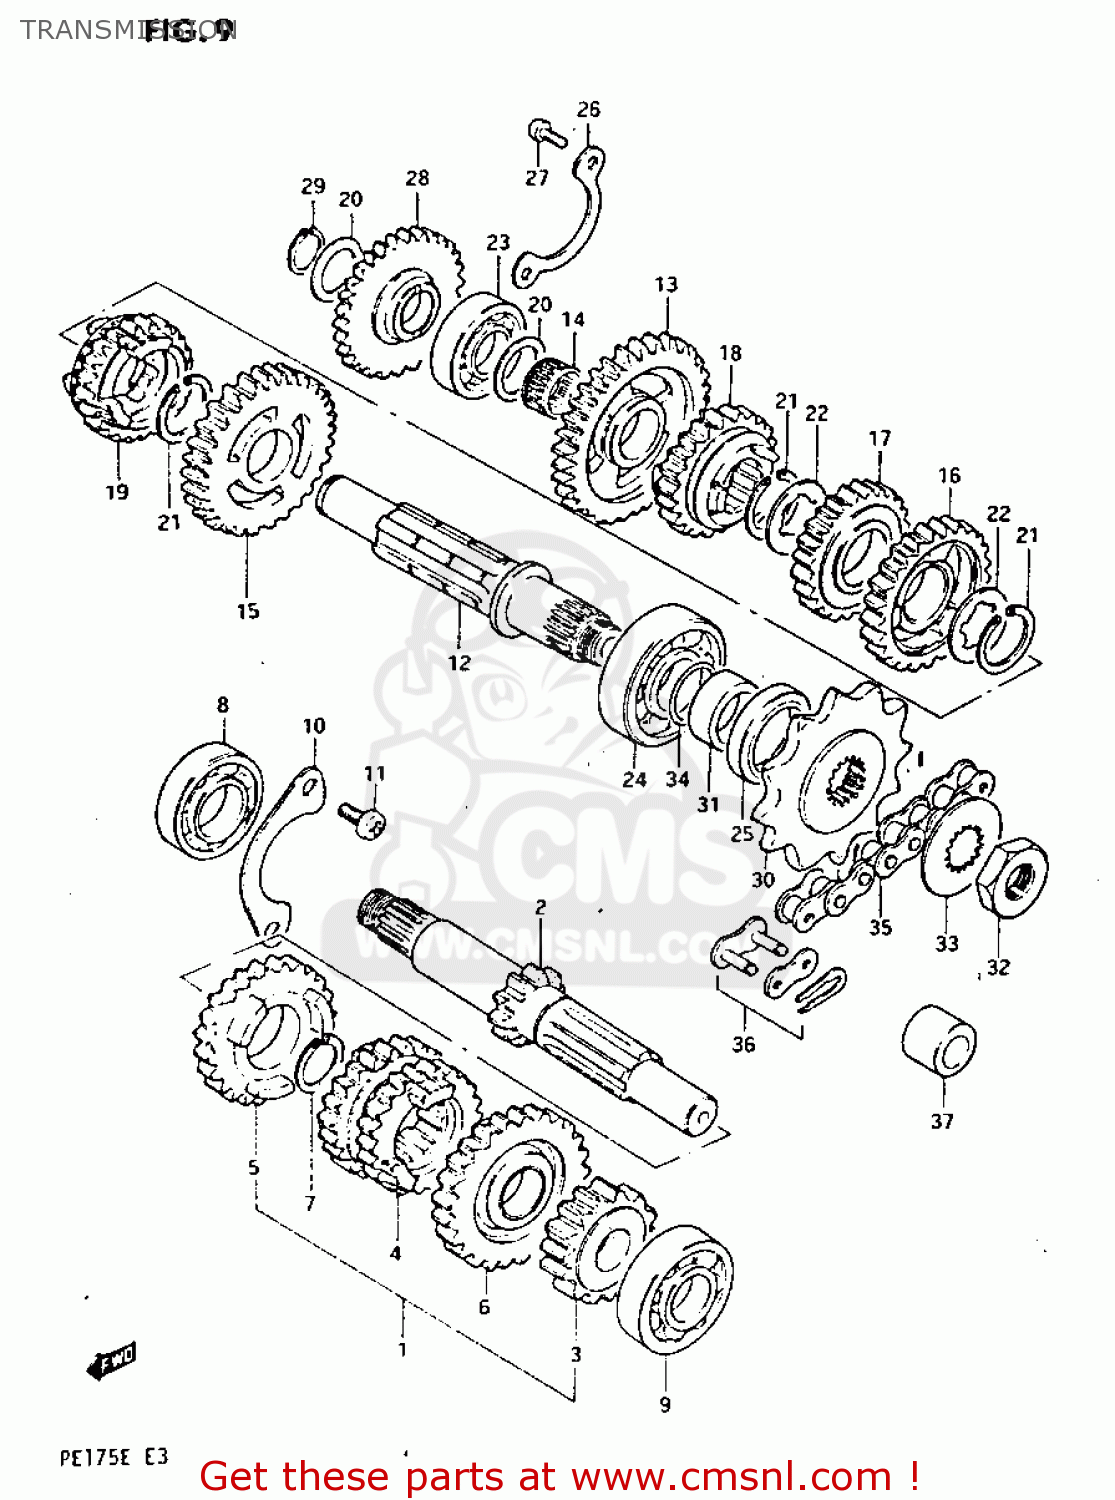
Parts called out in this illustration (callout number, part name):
1	SHAFT ASSEMBLY,COUNTER
2	SHAFT,COUNTER
3	GEAR,SECOND DRIVE
4	GEAR,THIRD DRIVE
5	GEAR,FIFTH DRIVE
6	GEAR,SIXTH DRIVE
7	CIRCLIP
8	BEARING(20X47X14)
9	BEARING
10	RETAINER,CNTR SHAFT BEARING
11	SCREW 6X12
12	SHAFT,DRIVE
13	GEAR,FIRST DRIVEN
14	ROLLER BEARING (15X19X9
15	GEAR,SECOND DRIVEN
16	GEAR,THIRD DRIVEN
17	GEAR,FOURTH DRIVEN
18	GEAR,FIFTH DRIVEN
19	GEAR,SIXTH DRIVEN
20	WASHER,THRUST
21	CIRCLIP
22	WASHER,LOCK
23	BEARING
24	BEARING(20X47X14)
25	SEAL,OIL(25X40X7)
26	PLATE,DRIVESHAFT BEARING
27	SCREW
28	GEAR,KICK STARTER IDLE
29	CIRCLIP,15MM
30	SPROCKET,ENGINE
31	SPACER(20X25X12.5)
32	NUT
33	WASHER,LOCK
34	O RING(D:1,ID:19.5)
35	CHAIN ASSEMBLY,DRIVE
36	JOINT ASSEMBLY,CHAIN
37	SPACER(12X20X15.3)
